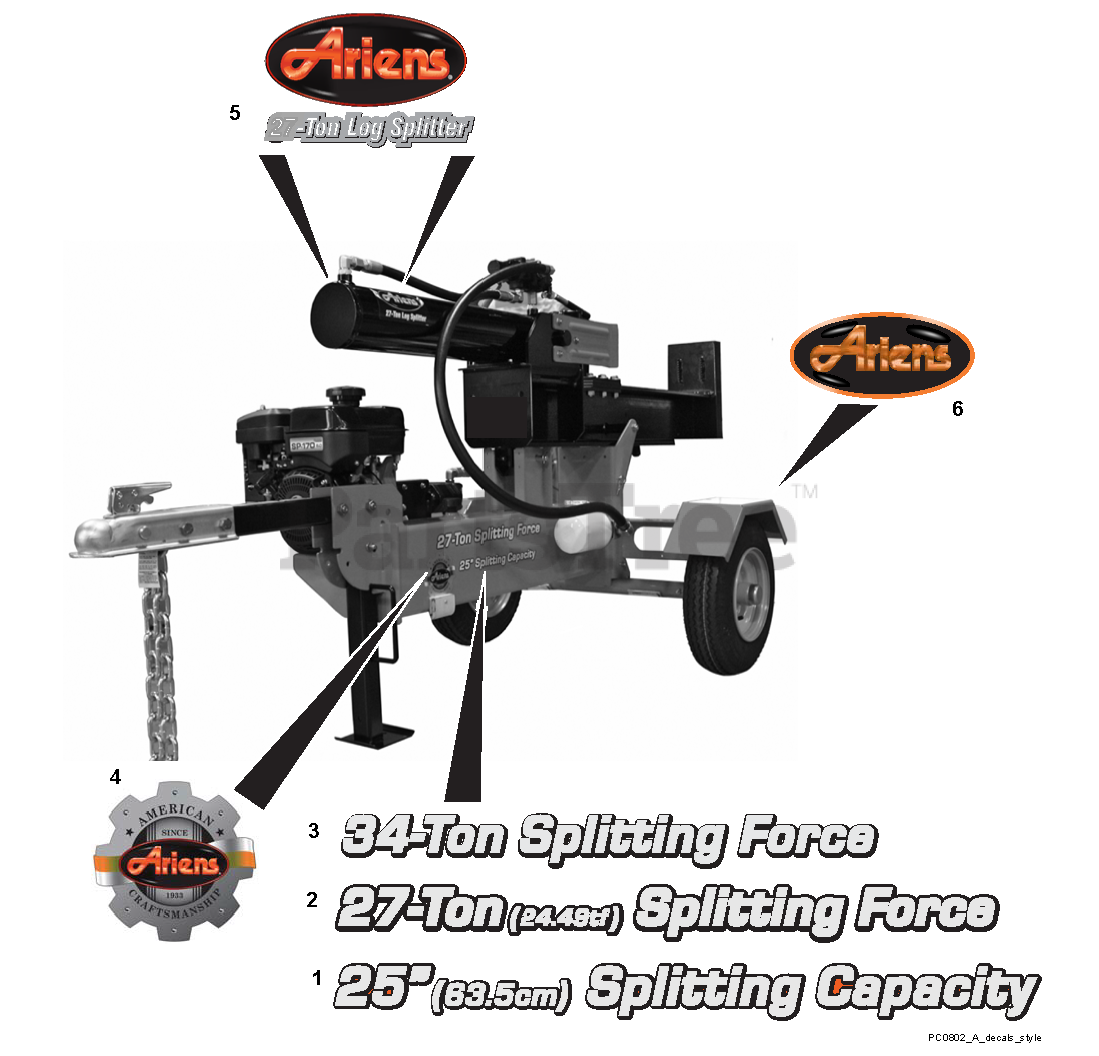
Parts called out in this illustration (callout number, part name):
1	DECAL,25"CAPACITY (ARIENS)
2	DECAL,27 TON FORCE (ARIENS)
3	DECAL, LOG SPLITTER-34 TONS
4	Decal, Ariens
5	DECAL, LOG SPLITTER-ARIENS 27T
6	DECAL, ARIENS JEWEL (LARGE)
